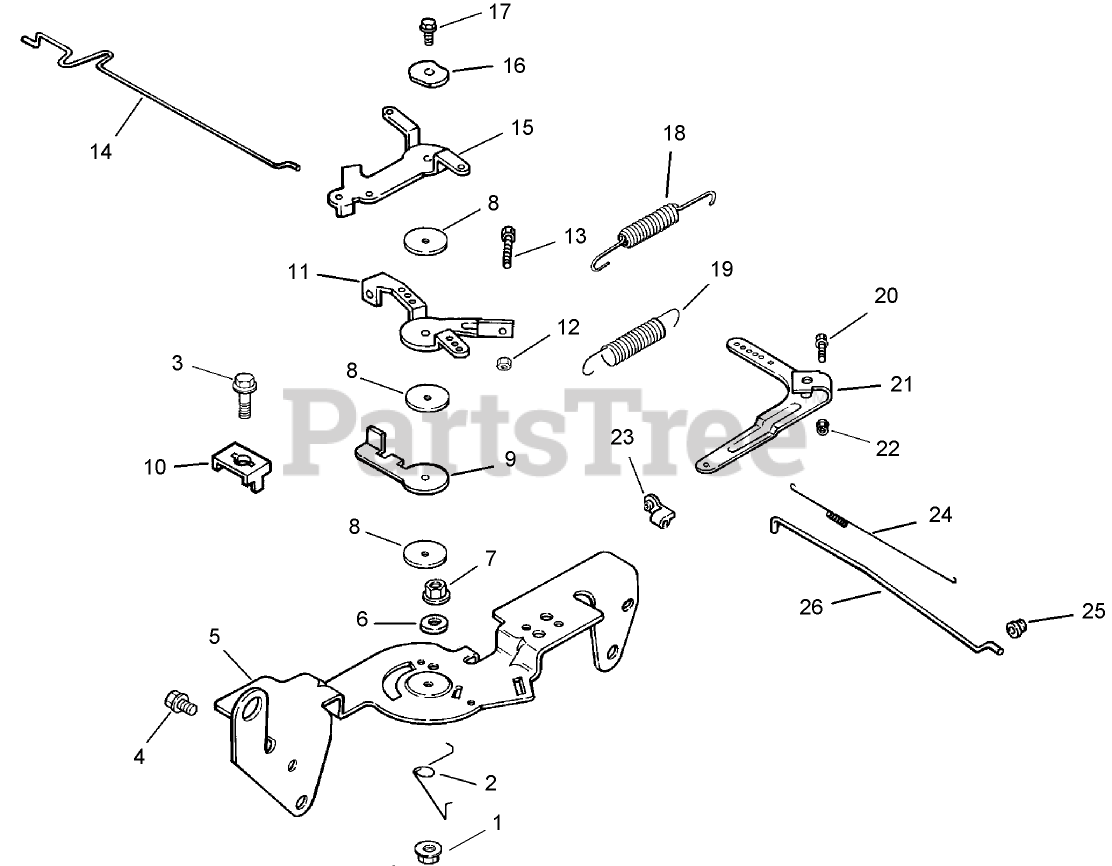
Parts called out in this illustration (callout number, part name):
1	NUT-LOCK (M5X.8)
2	SPRING-RETURN, CHOKE
3	SCREW-FLANGE, THREAD FORMING (M5X0.8X16)
4	SCREW-FLANGE, THREAD FORMING (M6X1.0X16)
5	Bracket-Control
6	Washer-Lock (.25)
7	Nut-HF (M5x0.8)
8	WASHER-FLAT (5.5MM)
9	Lever-Actuator, Throttle
10	CLAMP-CABLE
11	Lever-Control, Throttle
12	NUT (M4X0.7)
13	Screw (M4x0.7x30)
14	Linkage-Choke
15	LEVER-CHOKE
16	WASHER-SPRING (1/4)
17	SCREW-FLANGE, THREAD FORMING (M5X.8X20)
18	Spring-Limiter, Throttle
19	Spring-Governor
20	BOLT-SQ NECK, RD HD (M6X1.0X25)
21	Lever-Governor
22	NUT-FLANGE (M6X1.0)
23	BUSHING-RETAINING, LINKAGE
24	SPRING-LINKAGE
25	BUSHING-LINKAGE, THROTTLE
26	Linkage-Throttle
